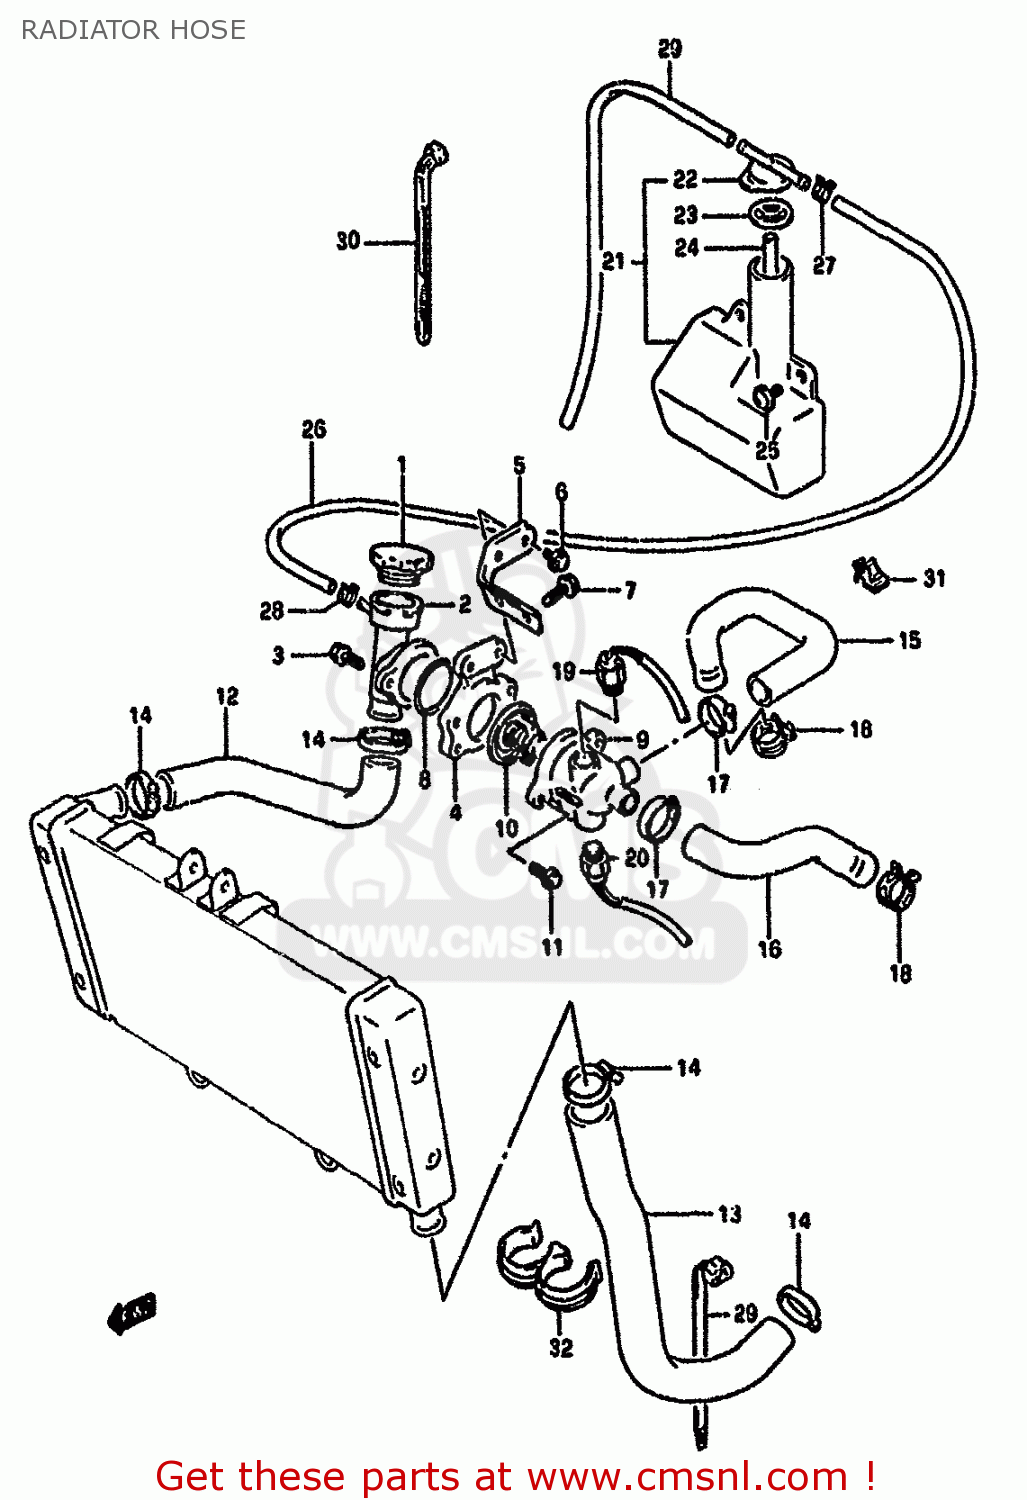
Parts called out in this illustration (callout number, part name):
1	CAP,RADIATOR 1.1
2	CONDUCTION,RADIATOR
3	BOLT 6X16
4	BRACKET,CONDUCTION
5	BRACKET,CONDUCTION BRAKE
6	BOLT
7	BOLT 6X20
8	O RING(D:2.4,ID:43.2)
9	CONNECTOR,THERMOSTAT INLET
10	THERMOSTAT,WATER
11	BOLT 6X20
12	HOSE,RADIATOR INLET
13	HOSE,RADIATOR OUTLET NO.1
14	CLAMP
15	HOSE,RADIATOR JOINT NO.1
16	HOSE,RADIATOR JOINT NO.2
17	CLAMP
18	CLAMP
19	SWITCH ASSY,WATER TEMP
20	SWITCH,RADIATOR FAN
21	TANK ASSY,RESERVOIR
22	CAP,WATER RESERVOIR TANK
23	RUBBER,WTR RSV TANK CAP
24	HOSE (7X12.1X600)
25	SCREW(6X16)
26	HOSE,RESERVOIR TANK INLET
27	CLIP
28	CLIP
29	HOSE
30	CLAMP(L:235)
31	CLAMP
32	CLAMP
